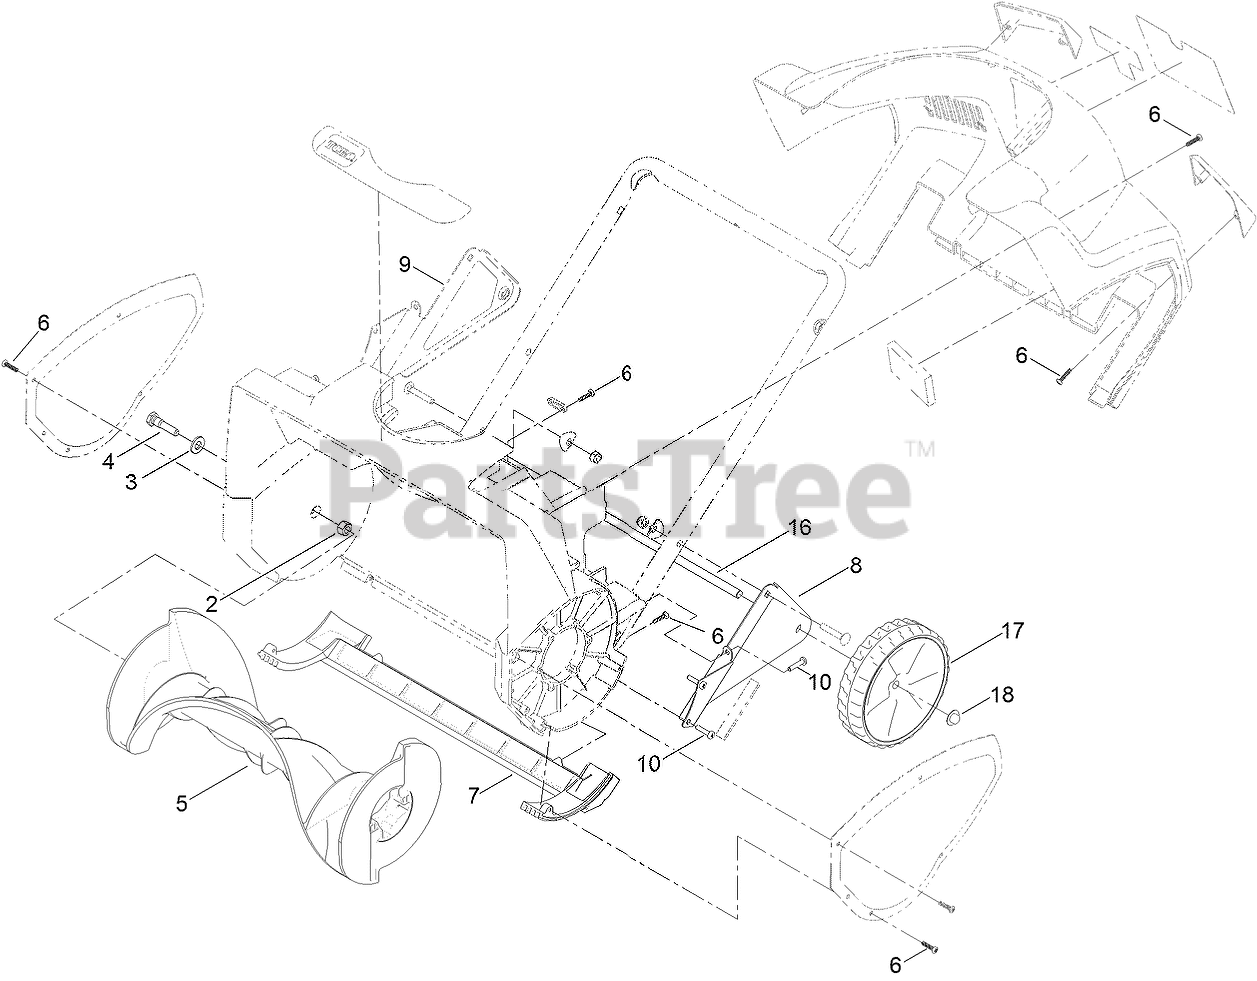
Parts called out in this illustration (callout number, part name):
2	NUT-LOCK
3	WASHER-FLAT
4	PIN-ROTOR
5	ROTOR ASM
6	SCREW-PPH
7	SCRAPER
8	BRACKET-WHEEL, LH
9	BRACKET-WHEEL, RH
10	SCREW-PPH
16	AXLE-WHEEL
17	WHEEL ASM
18	RETAINER-PUSH ON
